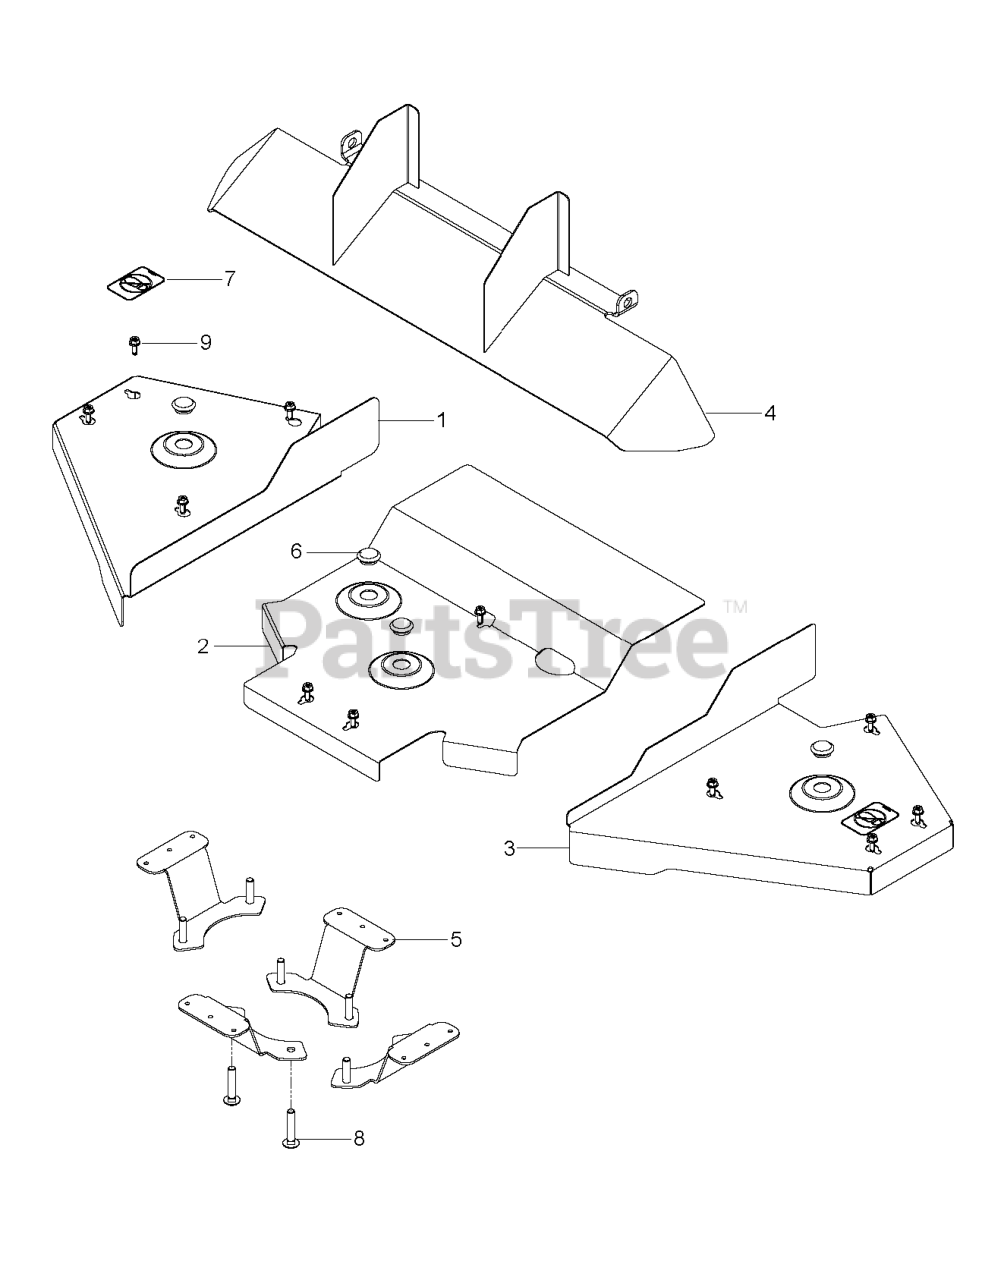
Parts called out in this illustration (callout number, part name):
1	GUARD.RIGHT.COMBI.48.B
2	GUARD CENTER.COMBI.48, BLACK
3	GUARD.LEFT.COMBI.48.BL
4	WLDT, DISCHARGE, COMBI BLK
5	BRACKET,BELT CVR,COMBI BLK
6	PLUG, BUTTON HOLE
7	DECAL, NO STEP
8	BOLT, CARRIAGE 5/16X1-1/4
9	SCREW- 1/4-20 X 5/8
